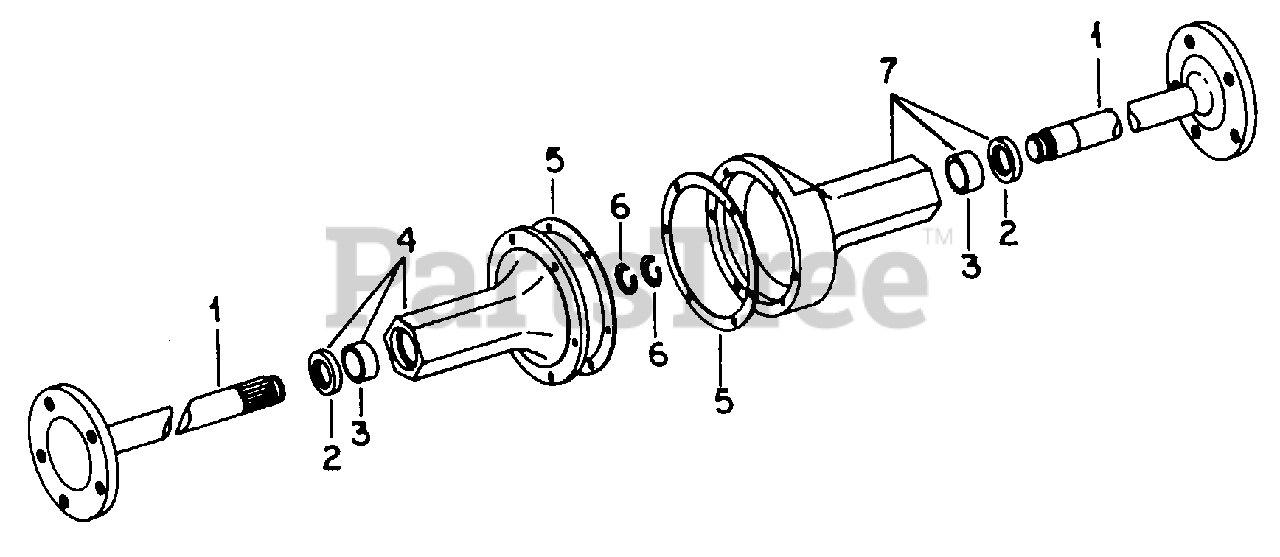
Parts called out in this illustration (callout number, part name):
1	Axle Assy, Rear
2	Seal, Oil
3	Bearing, Needle
4	Carrier Assy, Rear Axle, LH
5	Gasket, Carrier
6	Ring, Retaining
7	Carrier Assy, Rear Axle, RH
